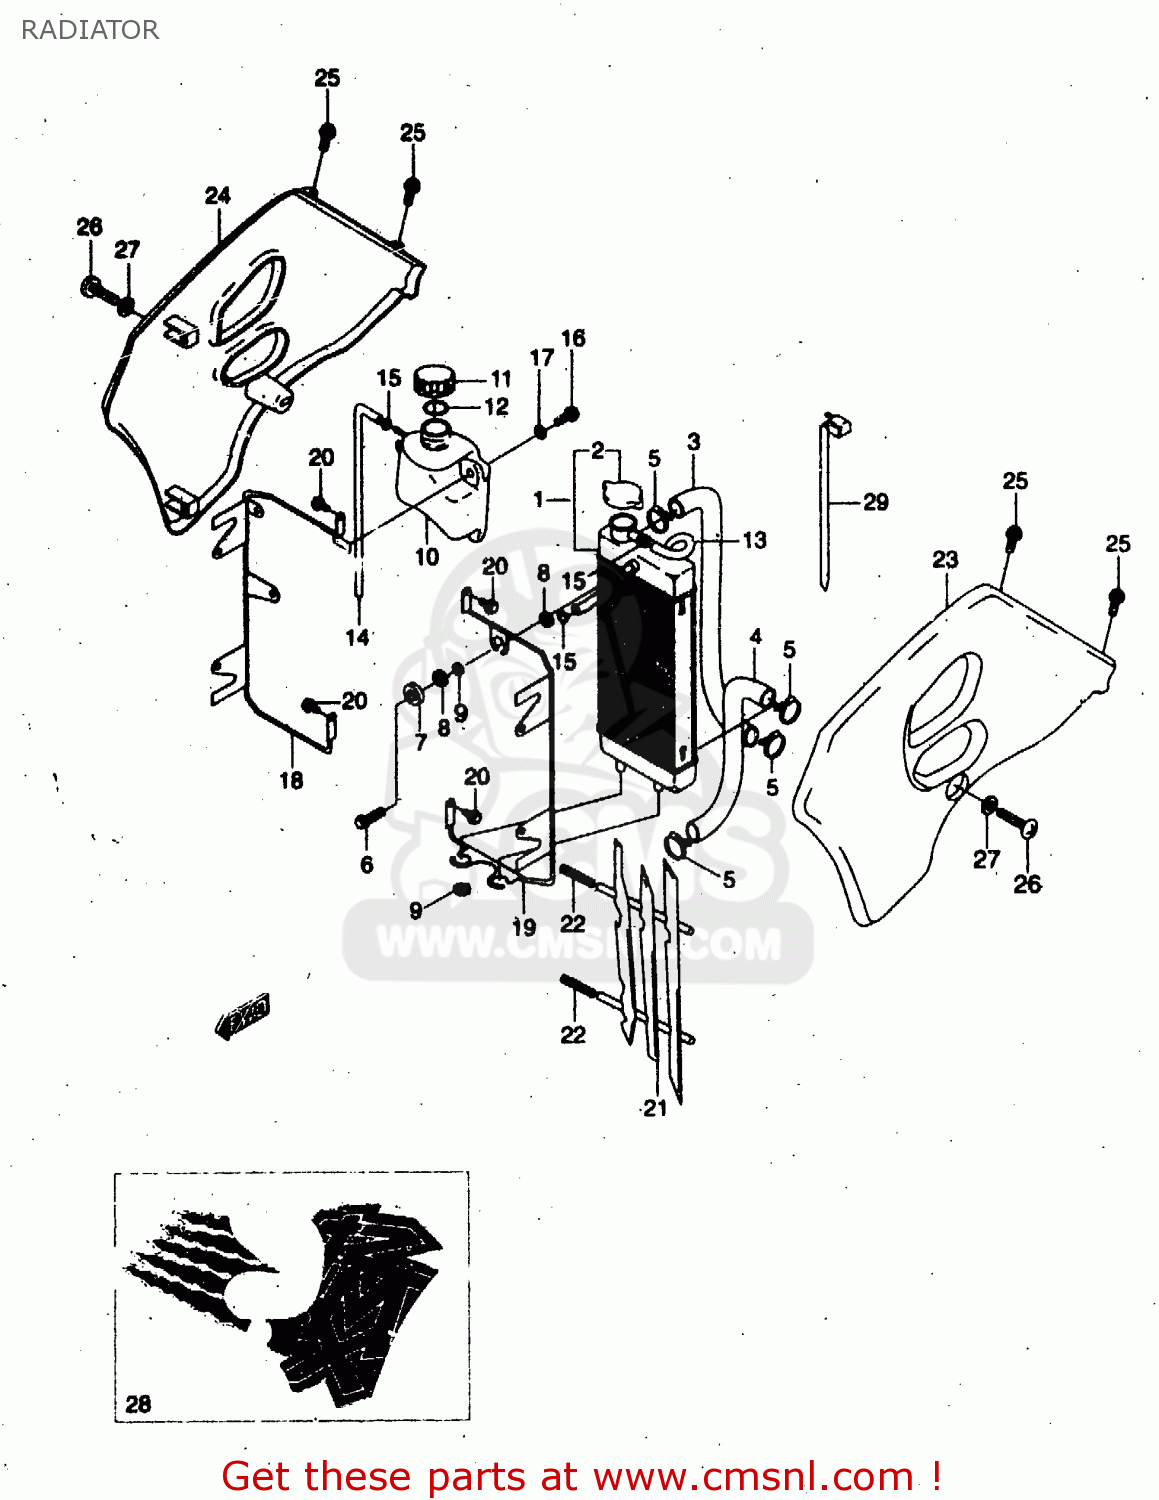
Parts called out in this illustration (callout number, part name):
1	RADIATOR, WATER
2	CAP, RADIATOR
3	HOSE, RADIATOR, INLET
4	HOSE, RADIATOR, OUTLET
5	CLAMP
6	BOLT
7	WASHER(6.5X18X1.6)
8	WASHER
9	CUSHION
10	TANK ASSY,RESERVOIR
11	CAP,RESERVOIR TANK
12	GASKET,RESERVOIR TANK CAP (NAS)
13	HOSE (L=360)
14	HOSE(5X8.2X600)
15	CLAMP
16	SCREW 6X16
17	WASHER(6.5X18X1.6)
18	BRACKET
19	HOLDER, RADIATOR
20	BOLT
21	LOUVER,RADIATOR
22	SPRING
23	COVER, RADIATOR, LH
24	COVER, RADIATOR, RH
25	SCREW
26	SCREW
27	WASHER(6.5X18X1.6)
28	EMBLEM SET (BLUE)
29	CLAMP(L:125)
